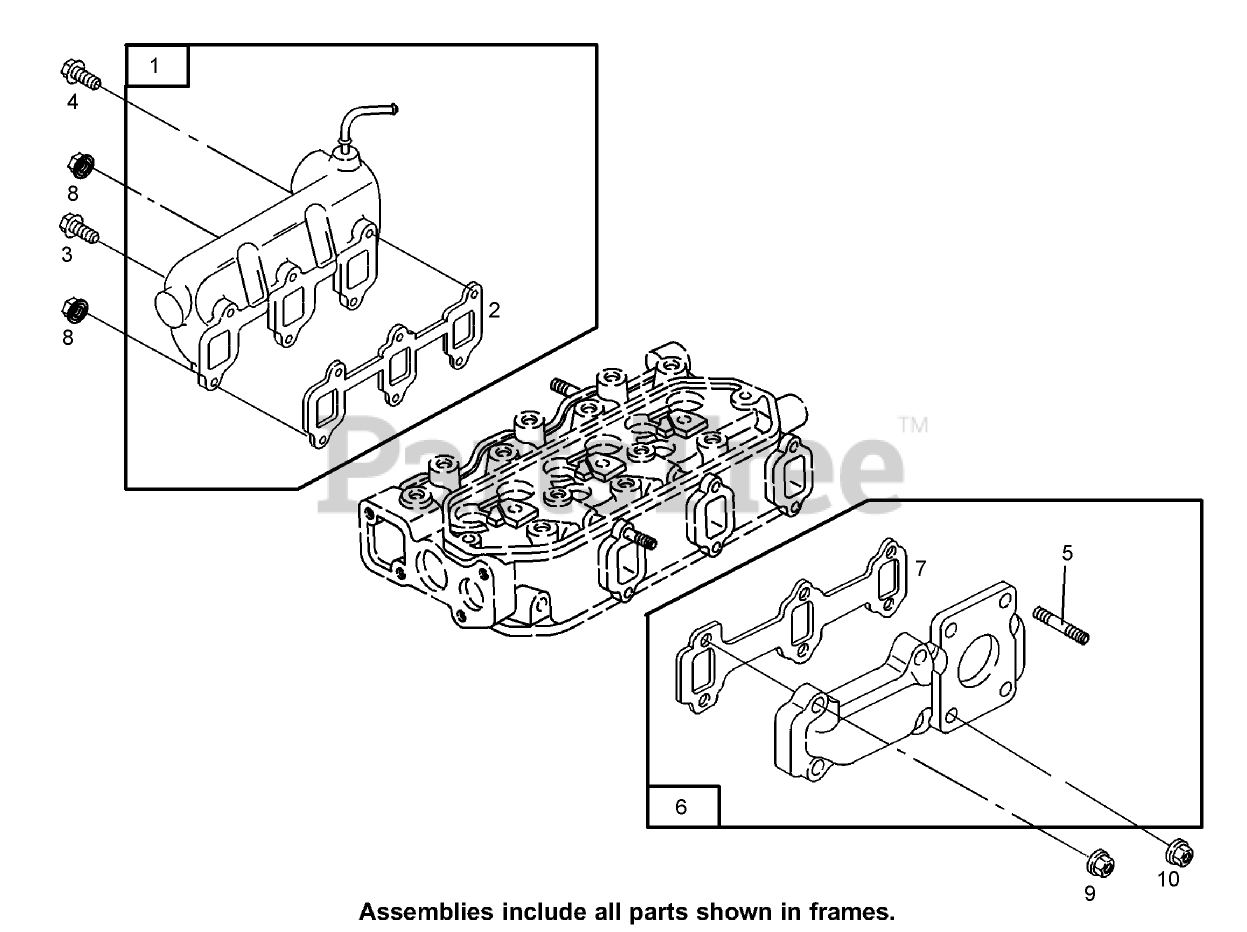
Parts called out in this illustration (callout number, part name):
1	MANIFOLD-INTAKE
2	GASKET-INTAKE
3	SCREW-HEX
4	SCREW-HEX
5	STUD-MANIFOLD, EXHAUST
6	MANIFOLD-EXHAUST
7	Gasket-Exhaust
8	NUT-HEX, METRIC
9	NUT-HEX, METRIC
10	NUT-HEX
